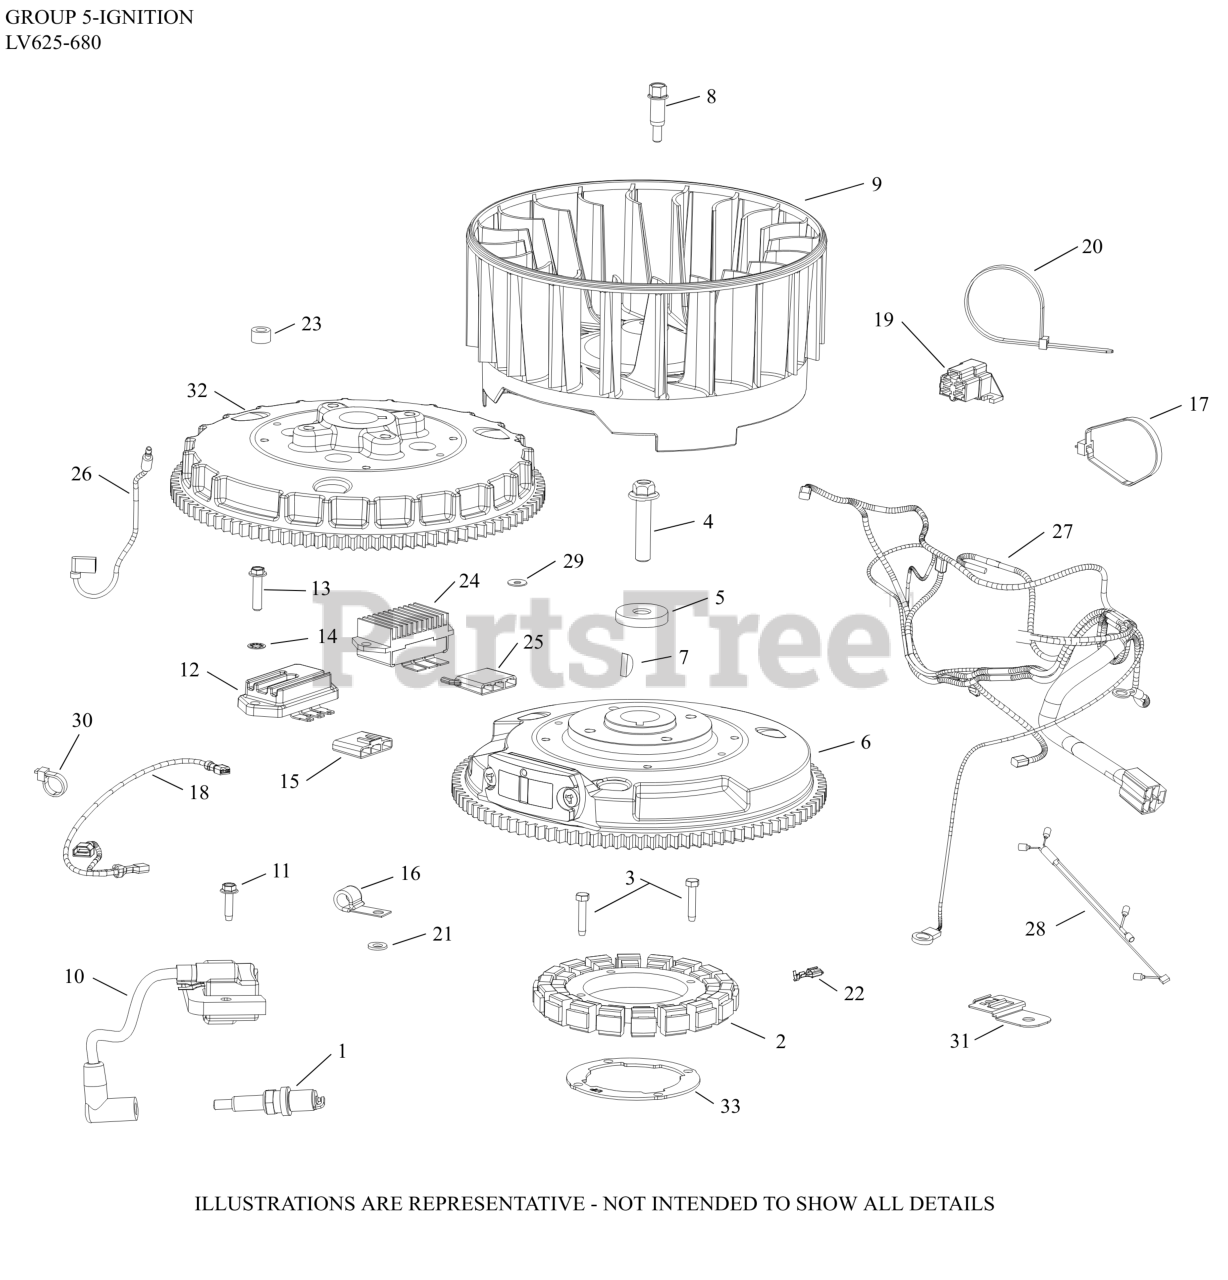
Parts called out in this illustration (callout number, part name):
1	SPARK PLUG
2	KIT, 15 / 20 AMP STATOR
3	SCREW, M5X0.8X25 - (#25086402S)
4	SCREW, FLG M10X1.5X45-USE 25 086 361-S
5	WASHER, FLAT 13/32"
6	FLYWHEEL (PAINTED)-USE 24 025 20-S
7	KEY, 3/16" X 5/8"
8	BOLT, SHOULDER
9	FAN - DISCONTINUED
10	MODULE, LV IGNITION - DISCONTINUED
11	SCREW, FLG THD FRM M5X.8X20-(#25086399S)
12	REG/RECT-15 AMP (KM)-USE 41 403 10-S
13	SCREW, HEX WASHER HEAD
14	WASHER, INT TOOTH LOCK 1/4"
16	CLIP, CABLE
17	TIE, CABLE
21	WASHER, FLAT 1/4" (O.D. 1/2")
27	HARNESS, WIRING - DISCONTINUED
